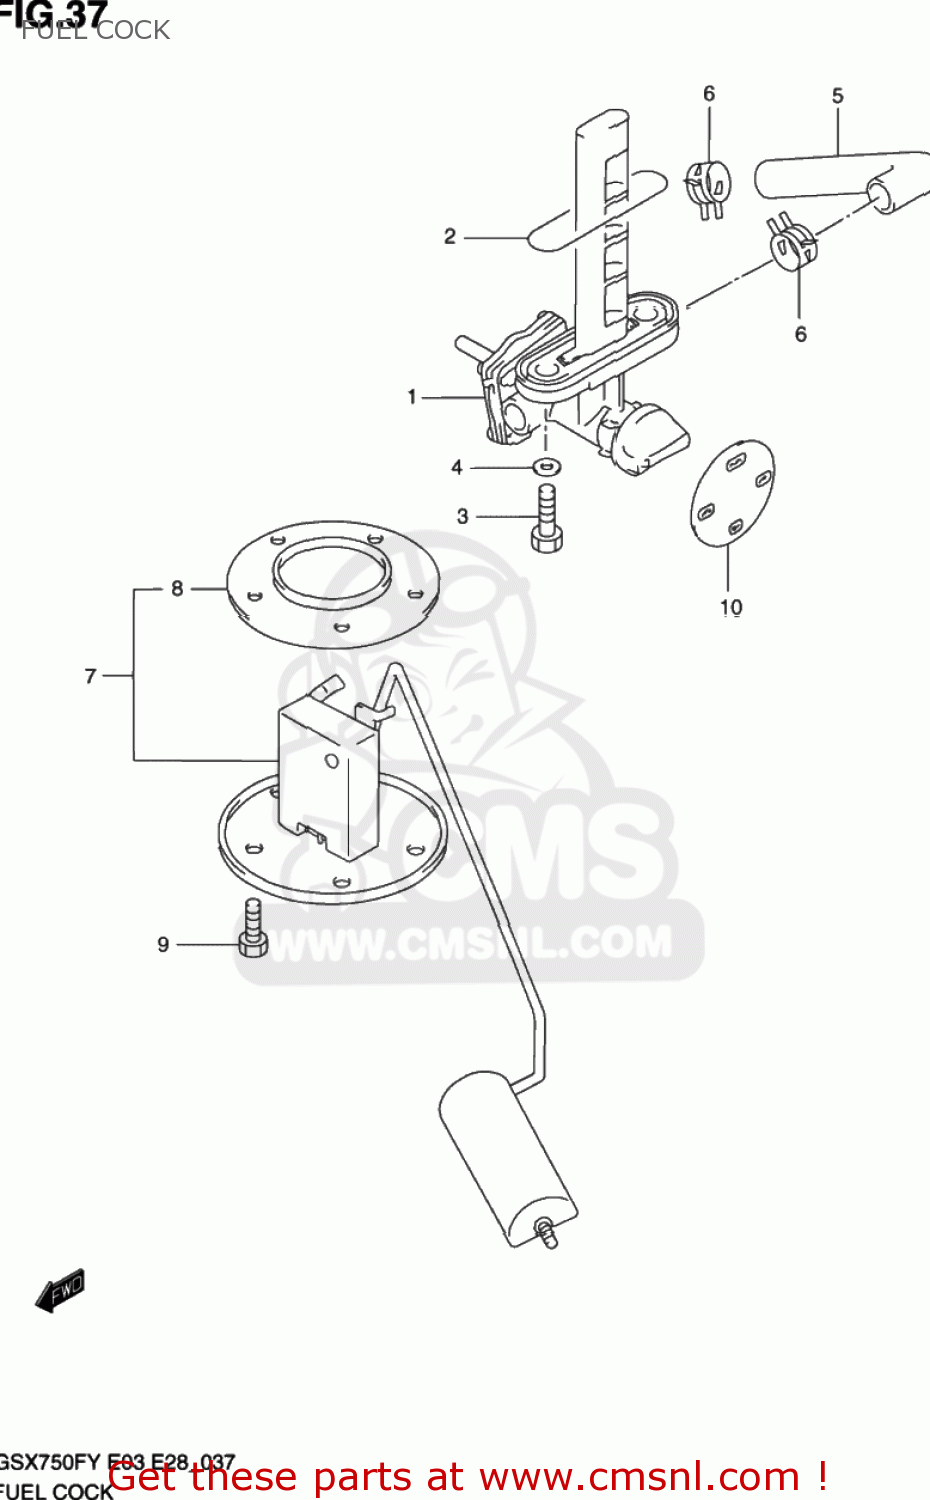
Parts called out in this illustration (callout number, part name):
1	COCK ASSEMBLY,FUEL
2	O RING
3	BOLT(6X20)
4	GASKET(6.4X11.5X0.8) (NAS)
5	HOSE,FUEL ON
6	CLIP
7	GAUGE ASSY,FUEL LEVEL SENDER
8	GASKET,FUEL LEVEL GAUGE (NAS)
9	BOLT 5X10
10	LABEL,FUEL COCK(GRAY)
